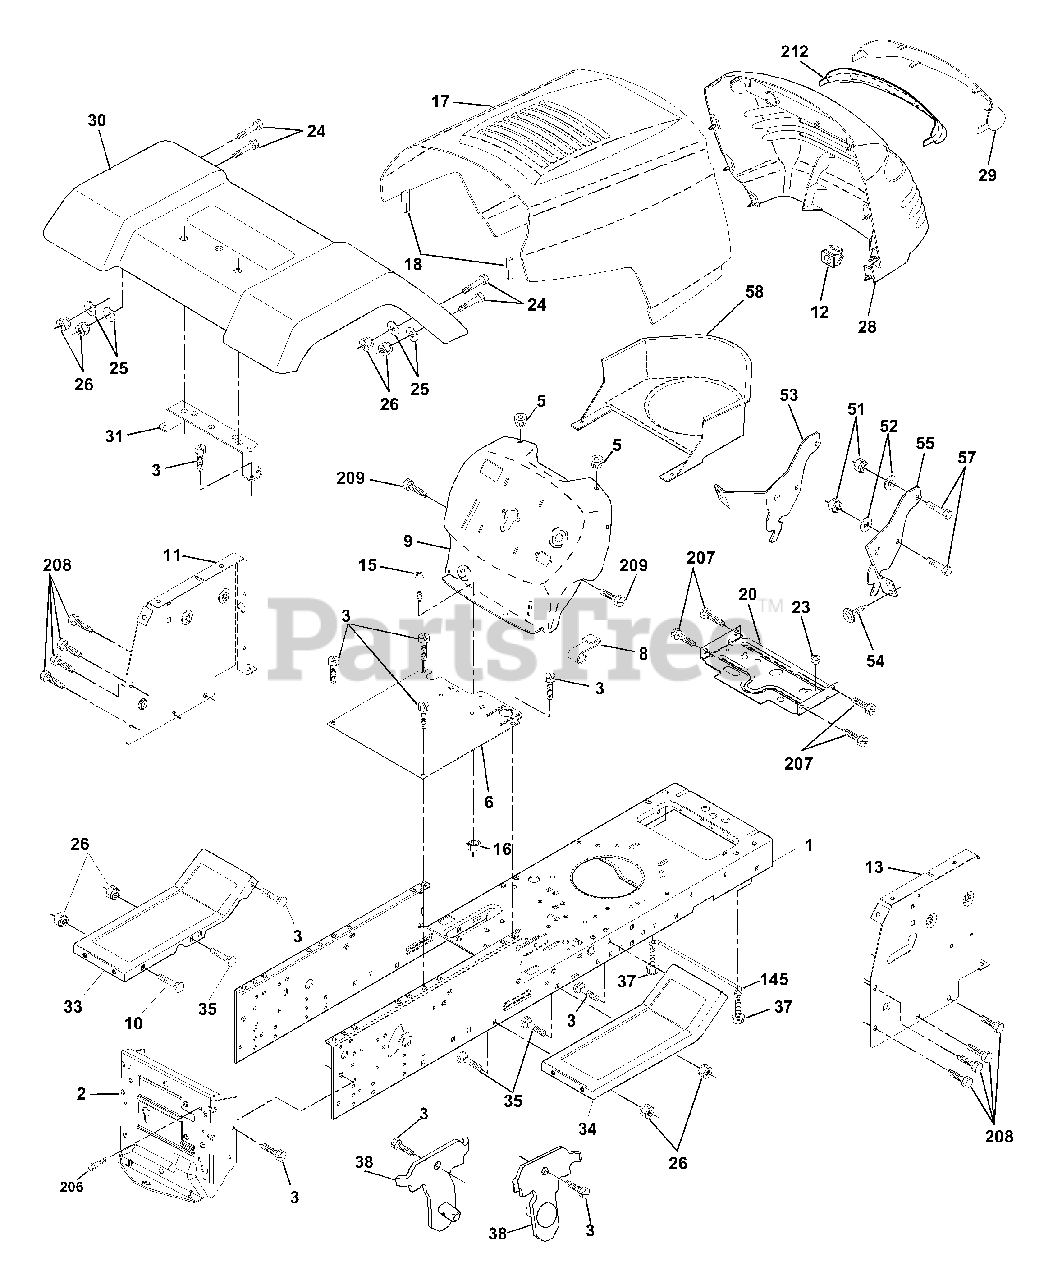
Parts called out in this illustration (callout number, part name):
2	Drawbar
3	Screw 3/8-16 x 3/4
5	Bumper Hood/Dash
6	Saddle Flat Lt
8	Clip Retainer Slide-On
9	Dash
10	Bolt Rd Hd Sqnk. 3/8-16 Unc x 1
11	Panel Asm. Dash Lh
12	Clip Tinnerman Grile P/L
13	Panel Dash Rh
15	Screw Mach Trhd 5/16-18 Unc x 3/4
16	Nut Keps 5/16-18 Unc
17	Hood
18	Bumper Hood
20	Plate Mtg Battery/Fuel Tank
23	Bushing Snap Nyl Blk Fuel Line
24	Bolt Fin Hex 3/8-16 Unc x 1 Gr. 5
25	Washer 13/32 x 13/16 x 12 Ga.
26	Nut Lock Hex w/Insert 3/8-16 UNC
28	Grill/Lens Asm
29	Lens Grille Private label
31	Bracket Fender
33	Footrest
34	Footrest
35	Bolt Rd Hd Sht. Sqnk. 3/8-16 x 3/4
37	Screw Thdrol 5/16-18 x 1/2 Tyt
38	Bracket Asm. Pivot Mower Rear
51	Nut Lock Hex W/Ins. 1/4-20
52	Washer 9/32 x 7/8 x 16 Ga.
53	Bracket Grille LH
54	Screw Hex Wshd 8-18 x 7/8
55	Bracket, Grille RH
57	Bolt Fin Hex 1/4-20 x .75
58	Air Duct Private Label
145	Rod Pivot Chassis/Hood
206	Bolt shoulder 5/16-18
207	Screw Thdrol 5/16-18 x 1/2 TYTT
208	Screw Thdrol 3/8-16 x 1/2
209	Screw Hex Wsh Thdrol 3/8-16
212	Insert Lens Reflector
